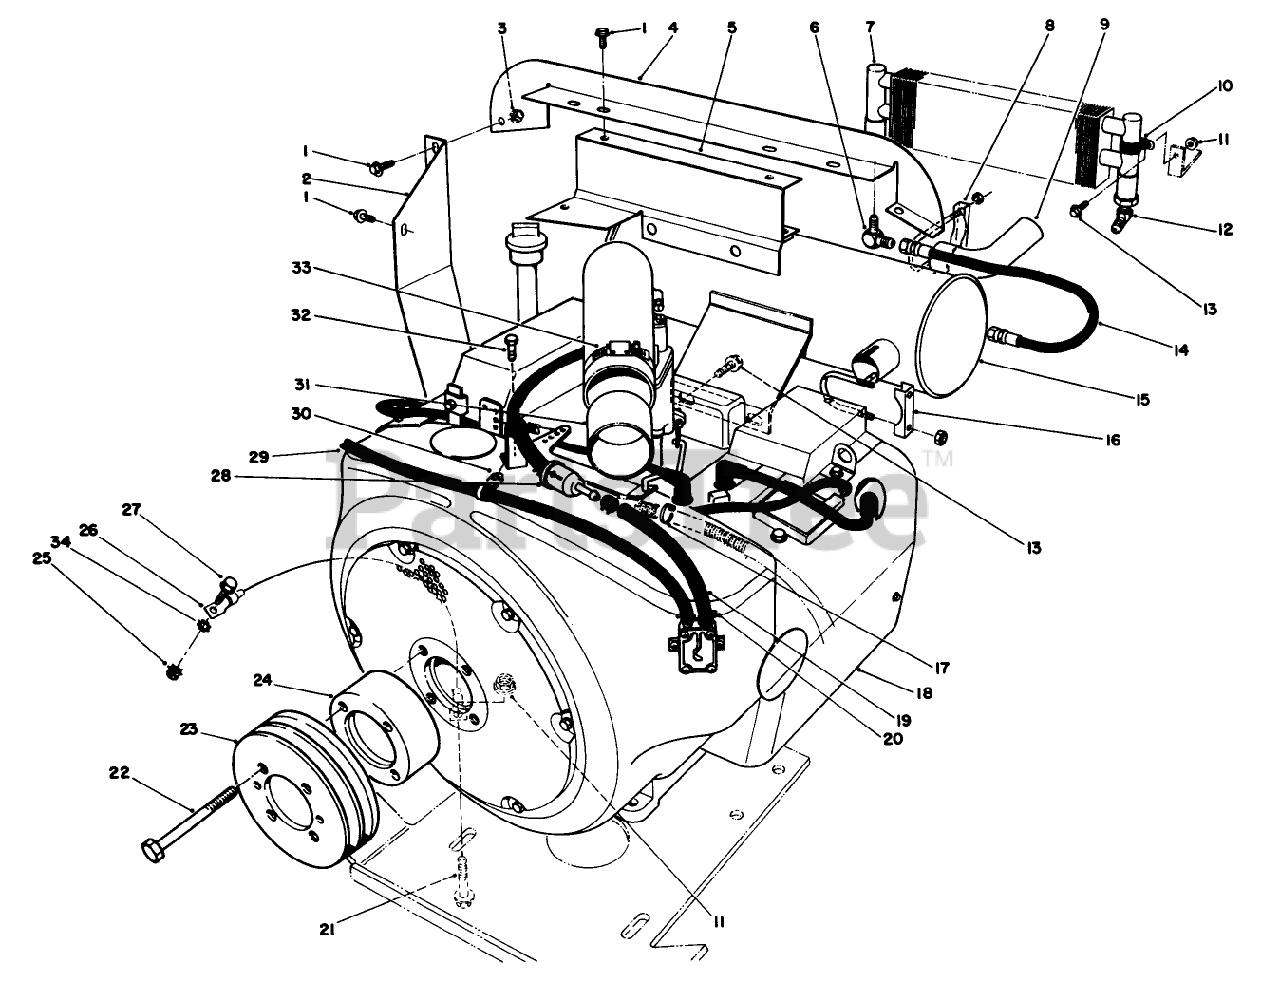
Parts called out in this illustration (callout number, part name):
1	SCREW-HHF
2	Shield-Heat
3	NUT-LOCK, NI
4	Shroud-Engine
5	Bracket-Shield Support
6	90DEG JIC FITTING
7	OIL COOLER
8	CLAMP
9	EXTENSION
10	CLAMP-R
11	NUT-HHF, WHIZ
12	ELBOW
13	SCREW-HHF
14	OIL HOSE ASM
15	MUFFLER
16	MUFFLER CLAMP
17	TIE-CABLE
18	Engine (Onan Model No. P220G-I/10808C
19	Hose
20	CLAMP-HOSE
21	SCREW-HHF
22	SCREW
23	Pulley-Engine
24	PULLEY SPACER
25	NUT-KEPS
26	WIRE ASM
27	SCREW-HHF
28	FILTER-FUEL
29	HOSE
30	R CLAMP
31	AIR CLEANER ADAPTER
32	SCREW-HWHTF
33	CLAMP-HOSE
34	WASHER-LOCK/EXT
